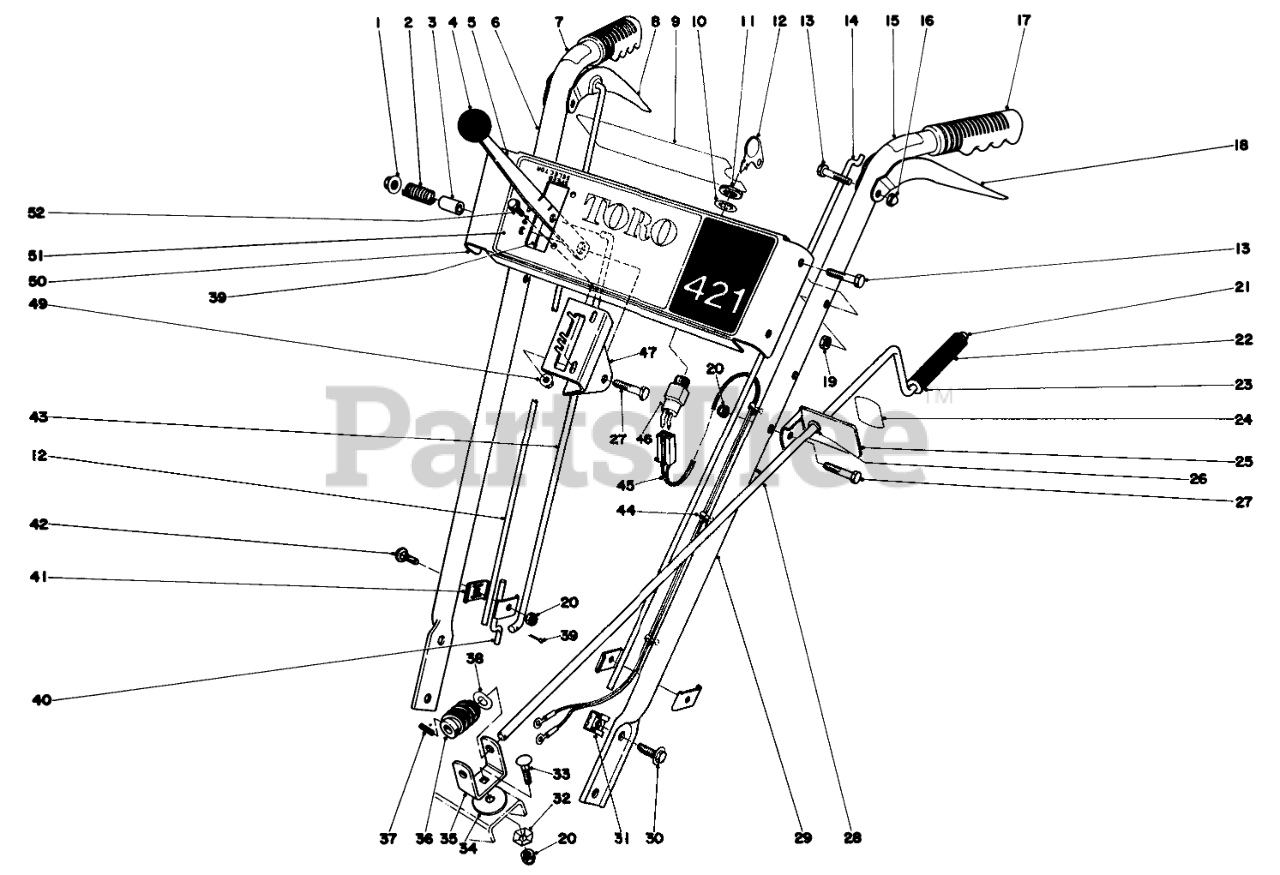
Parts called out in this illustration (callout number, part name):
1	NUT-HF
2	SPRING
3	Spacer-Speed Control
5	SPEED SELECTOR B
6	Handle Ring
7	Decal-Traction Engage
8	Lever-Auger Control
9	Decal-Escutcheon Back
10	WASHER-TOOTH, INTERNAL
11	NUT-HH
12	Key
13	SCREW-HH
14	Link Upper
15	Decal-Auger Engage
16	NUT-CAP
17	Grip
18	Lever-Traction Control
20	NUT-LOCK, NI
21	RETAINER-PUSH ON
22	CHUTE CONTROL GRIP
23	WASHER-FLAT
24	CHUTE DECAL
25	BRACKET-ROD, CHUTE
26	Bushing
27	SCREW-HH
28	ROD CHUTE CONTROL
29	Handle Left
30	SCREW-HHF
32	WASHER-LOCK
33	BOLT-CARR
34	WASHER
35	WORM BRACKET
36	GEAR-WORM, CHUTE
37	PIN-SPRING
38	WASHER-SPRING
39	PIN-COTTER
40	Link-Auger Lower
41	CLAMP CONTROL ROD
42	BOLT-CARR
43	Rod Speed Selector
44	TIE-CABLE
45	WIRE HARNESS
46	SWITCH-ON / OFF
47	Mount-Speed Selector
49	NUT-LOCK, HHF
50	Panel-Escutcheon
51	Decal-Escutcheon
52	SCREW-HH
